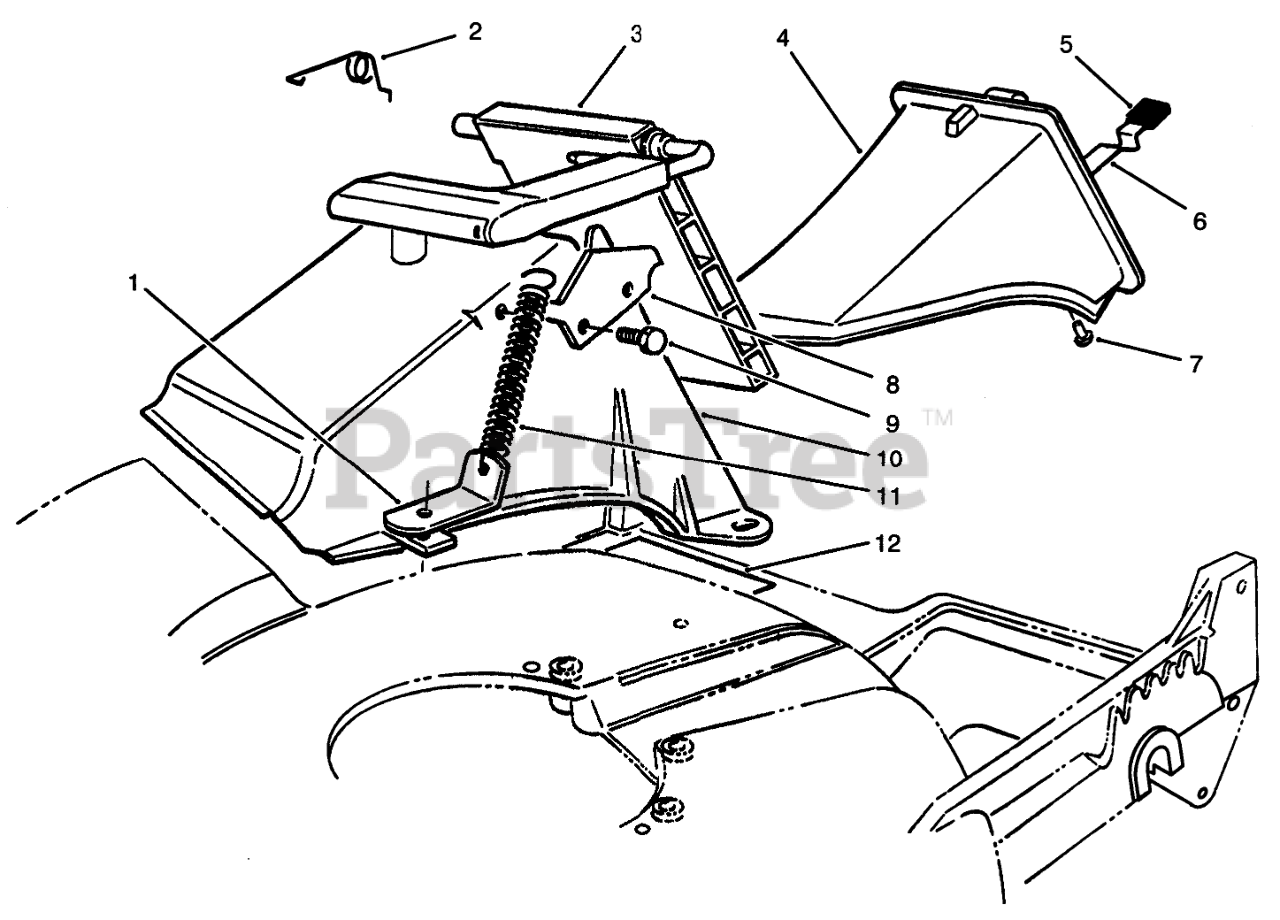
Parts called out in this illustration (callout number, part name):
1	BRACKET-SPRING
2	RETAINER-DOOR
3	DISCHARGE DOOR ASM
4	Plug Assembly (Incl. Ref. #5-7)
5	GRIP-LATCH
6	LATCH-PLUG, DISCHARGE
7	RIVET-HEAD, FLAT
8	LATCH-PLATE
9	SCREW-PLASTITE
10	TUNNEL-DISCHARGE
11	SPRING-DOOR
12	DECAL - CAUTION
